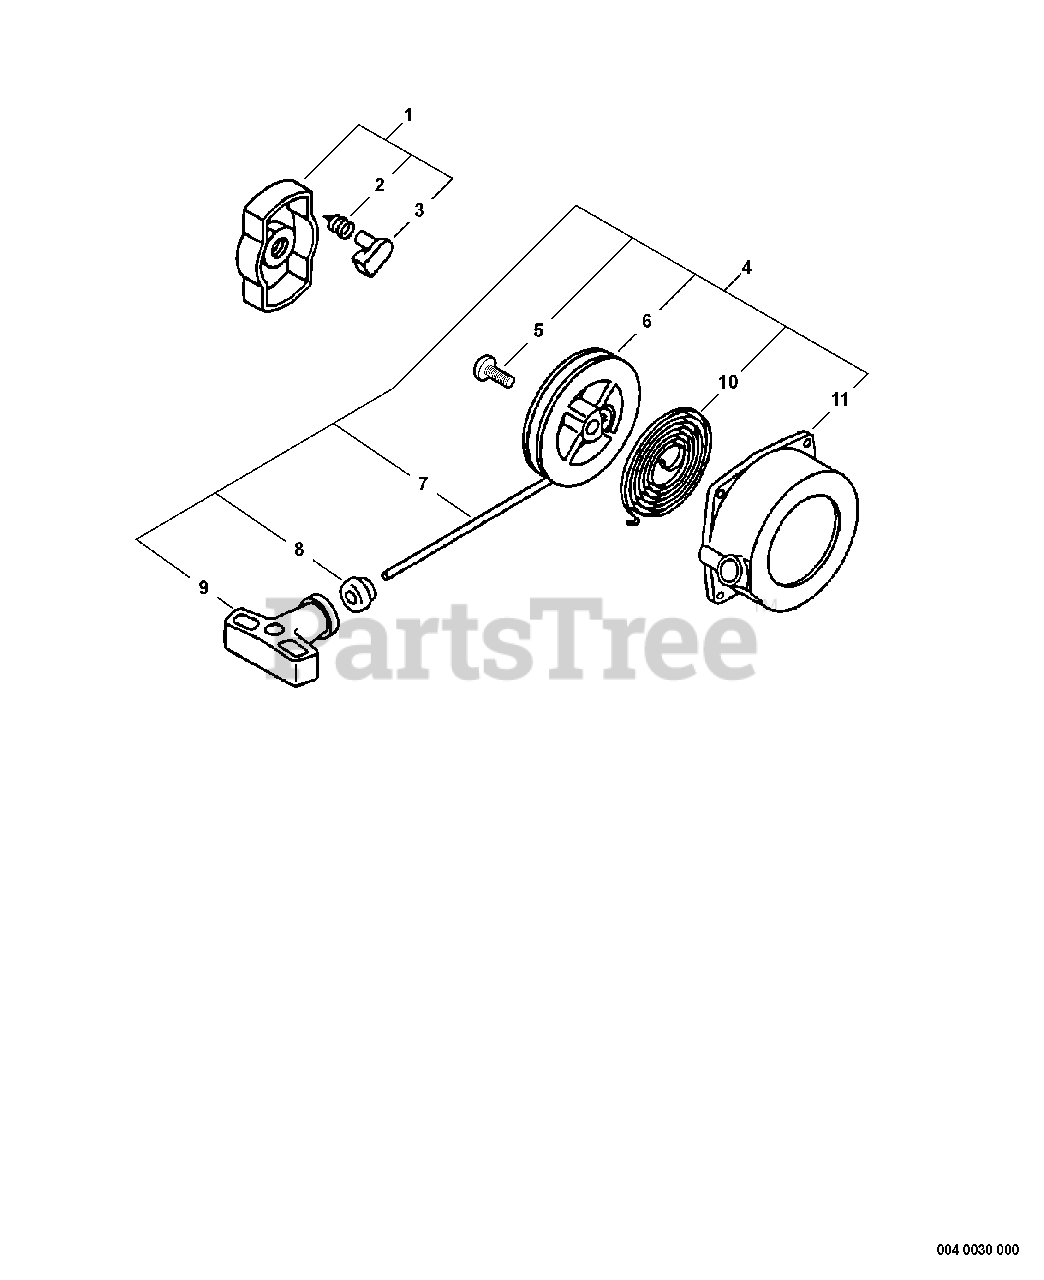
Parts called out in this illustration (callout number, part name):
1	STARTER PAWL ASSY
2	SPRING, RETURN
3	PAWL, STARTER - BLACK
4	STARTER ASSY
6	REEL, ROPE
7	ROPE, STARTER - 3X1000
8	GUIDE, ROPE
9	GRIP, STARTER
10	SPRING, REWIND
11	CASE, STARTER
